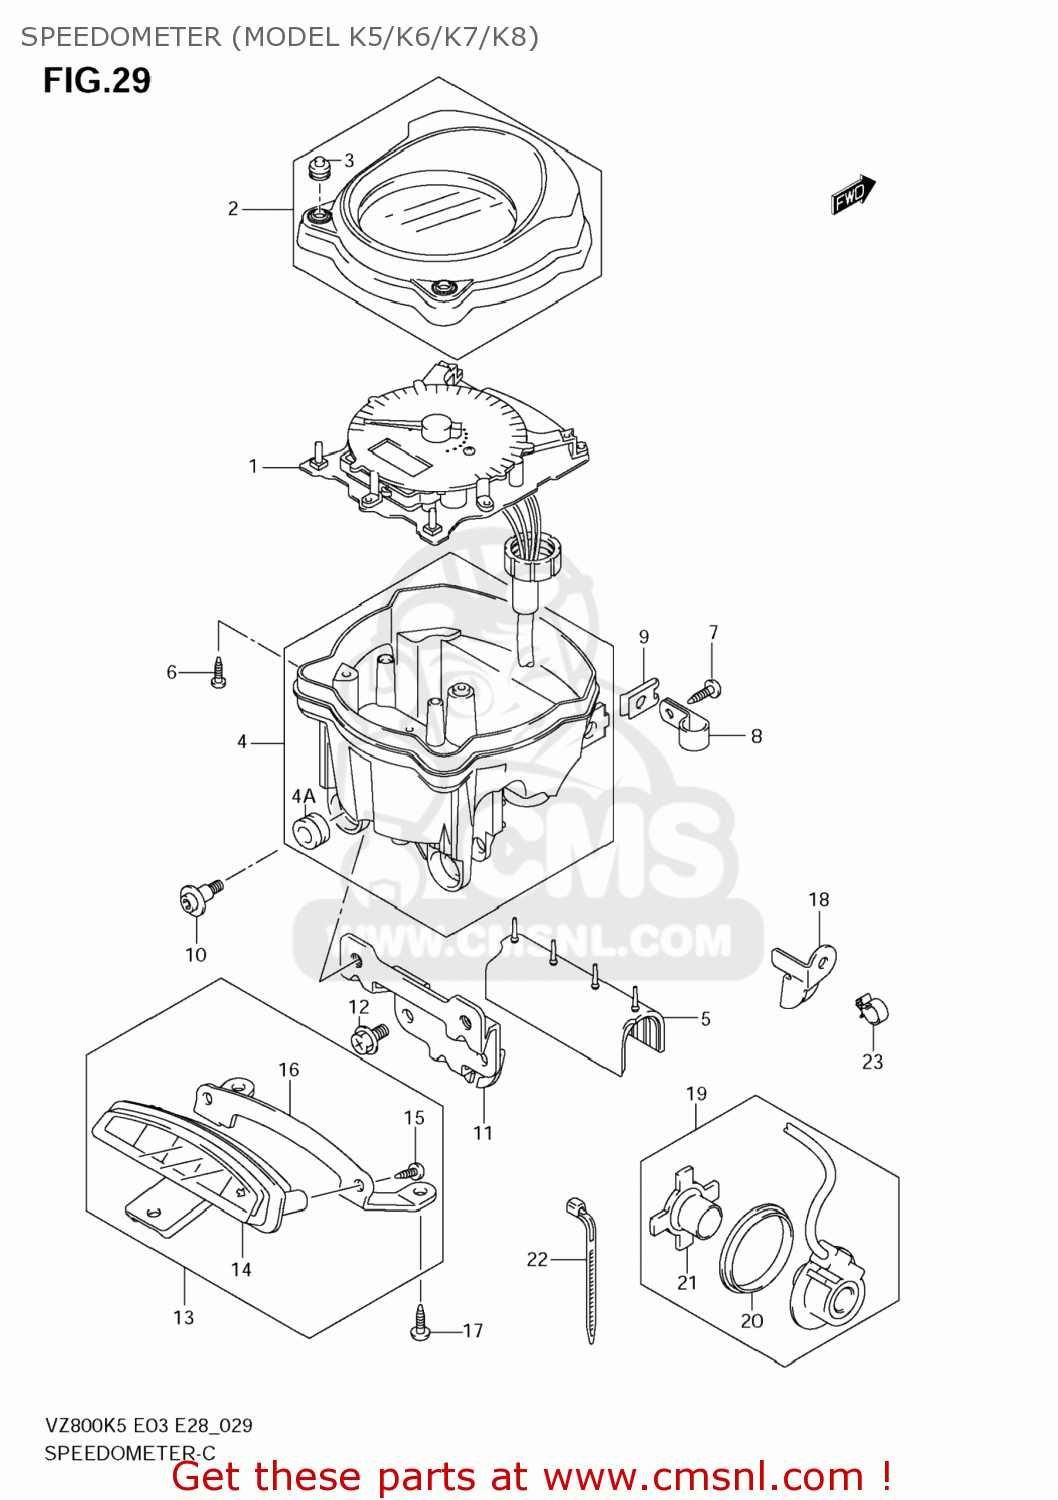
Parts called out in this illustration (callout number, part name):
1	SPEEDOMETER
2	CASE ASSY,UPR
3	RUBBER,SWITCH
4	CASE ASSY,LWR
4A	CUSHION,METER
5	ATTACHMENT,RUBBER
6	SCREW(3X16)
7	SCREW
8	CLAMP
9	NUT,COWL
10	SCREW,SPEEDOMETER
11	BRACKET,SPEEDOMETER
12	SCREW
13	BOX ASSY,PILOT LAMP
14	CASE,UNIT
15	SCREW
16	BRACKET,PILOT LAMP
17	SCREW
18	GUIDE,SPEED SENSOR LEAD
19	SENSOR,SPEED
20	SEAL,OIL(44X55X6)
21	MAGNETO
22	CLAMP(L:145)
23	CLAMP
